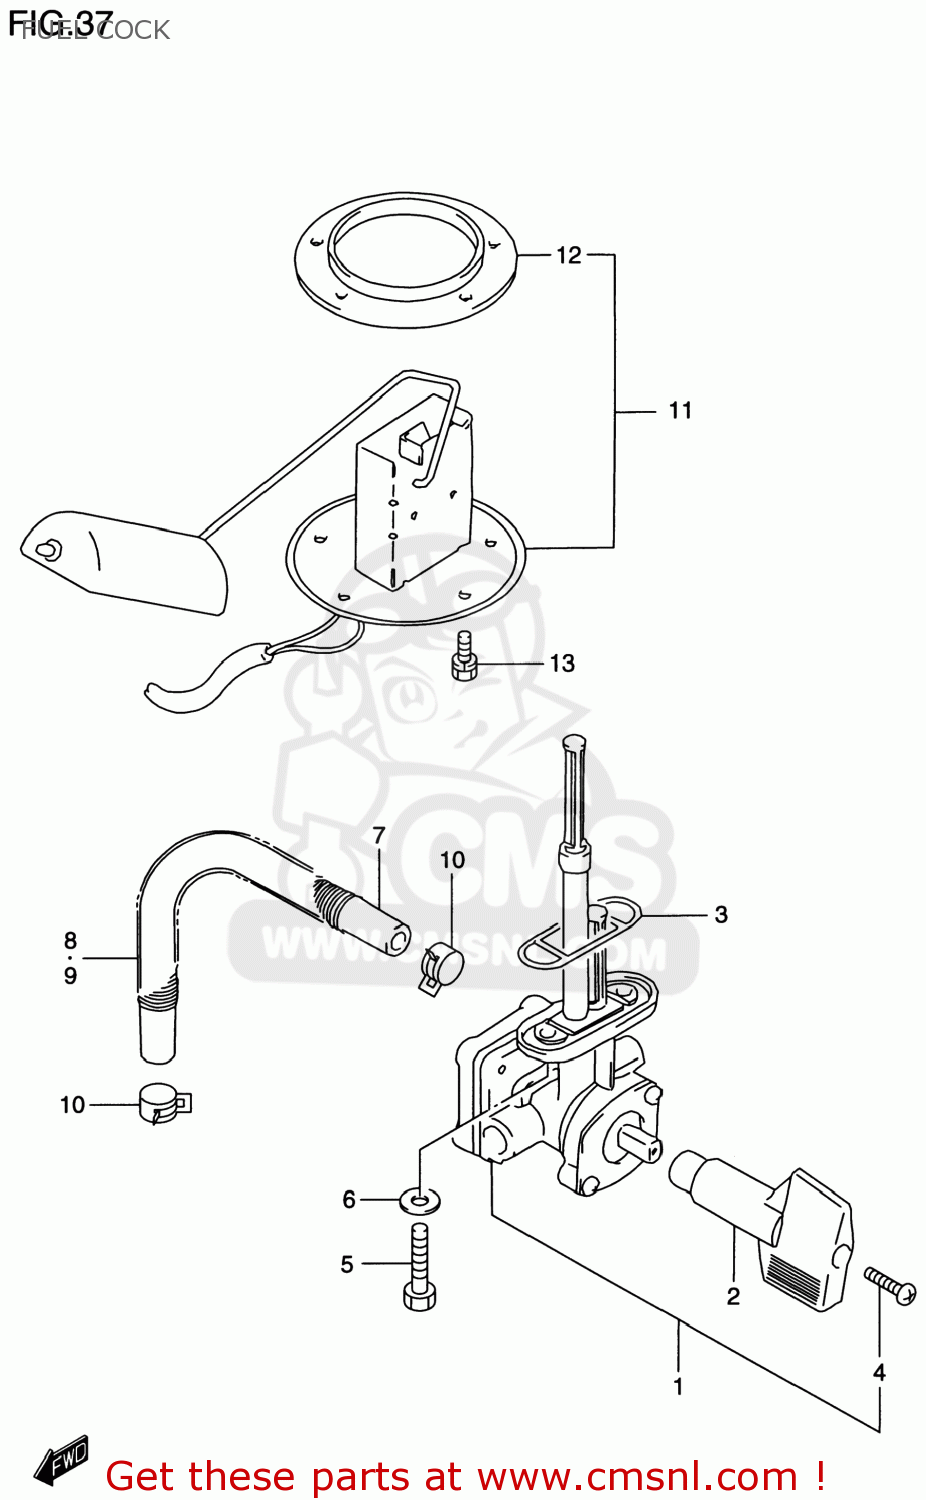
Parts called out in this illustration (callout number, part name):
1	COCK ASSEMBLY,FUEL
2	LEVER,FUEL COCK
3	GASKET,JOINT (NAS)
4	SCREW
5	BOLT(6X20)
6	GASKET(6.4X11.5X0.8) (NAS)
7	HOSE(7X12X600)
8	PROTECTOR(14.5X15.5X600)
9	SPRING
10	CLIP
11	GAUGE ASSEMBLY,FUEL LEVEL
12	GASKET,FUEL LEVEL GAUGE (NAS)
13	BOLT 5X10
